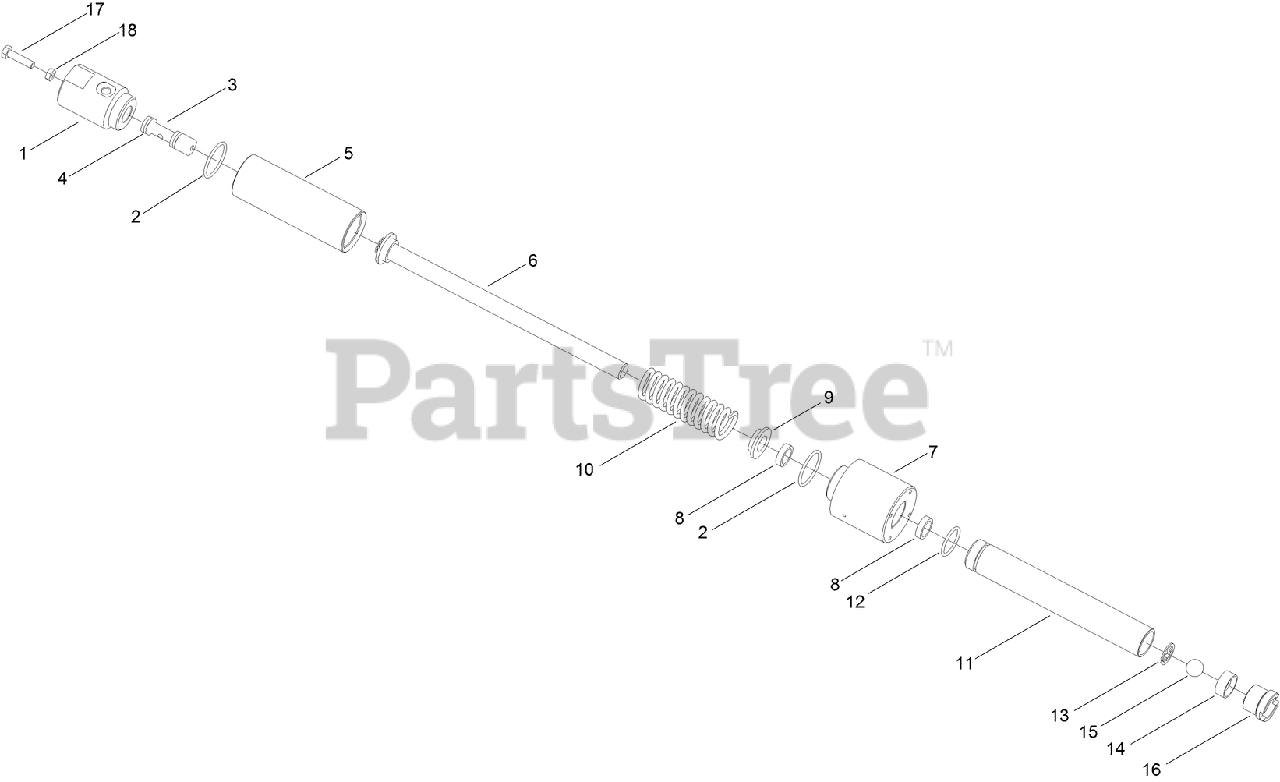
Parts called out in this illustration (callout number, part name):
1	CAP-CYLINDER
2	SEAL-O RING
3	SPOOL-ADJUSTING
5	BARREL-CYLINDER
6	PLUNGER
7	BODY-PUMP
8	SEAL-DEEP
9	GUIDE-ROD
10	SPRING
11	BARREL-PUMP
12	SEAL-O RING
13	CLIP-RETAINER
14	VALVE-SEAT
15	BALL-STEEL, STAINLESS
16	TUBE-INLET
17	SCREW-HH
18	NUT-JAM
